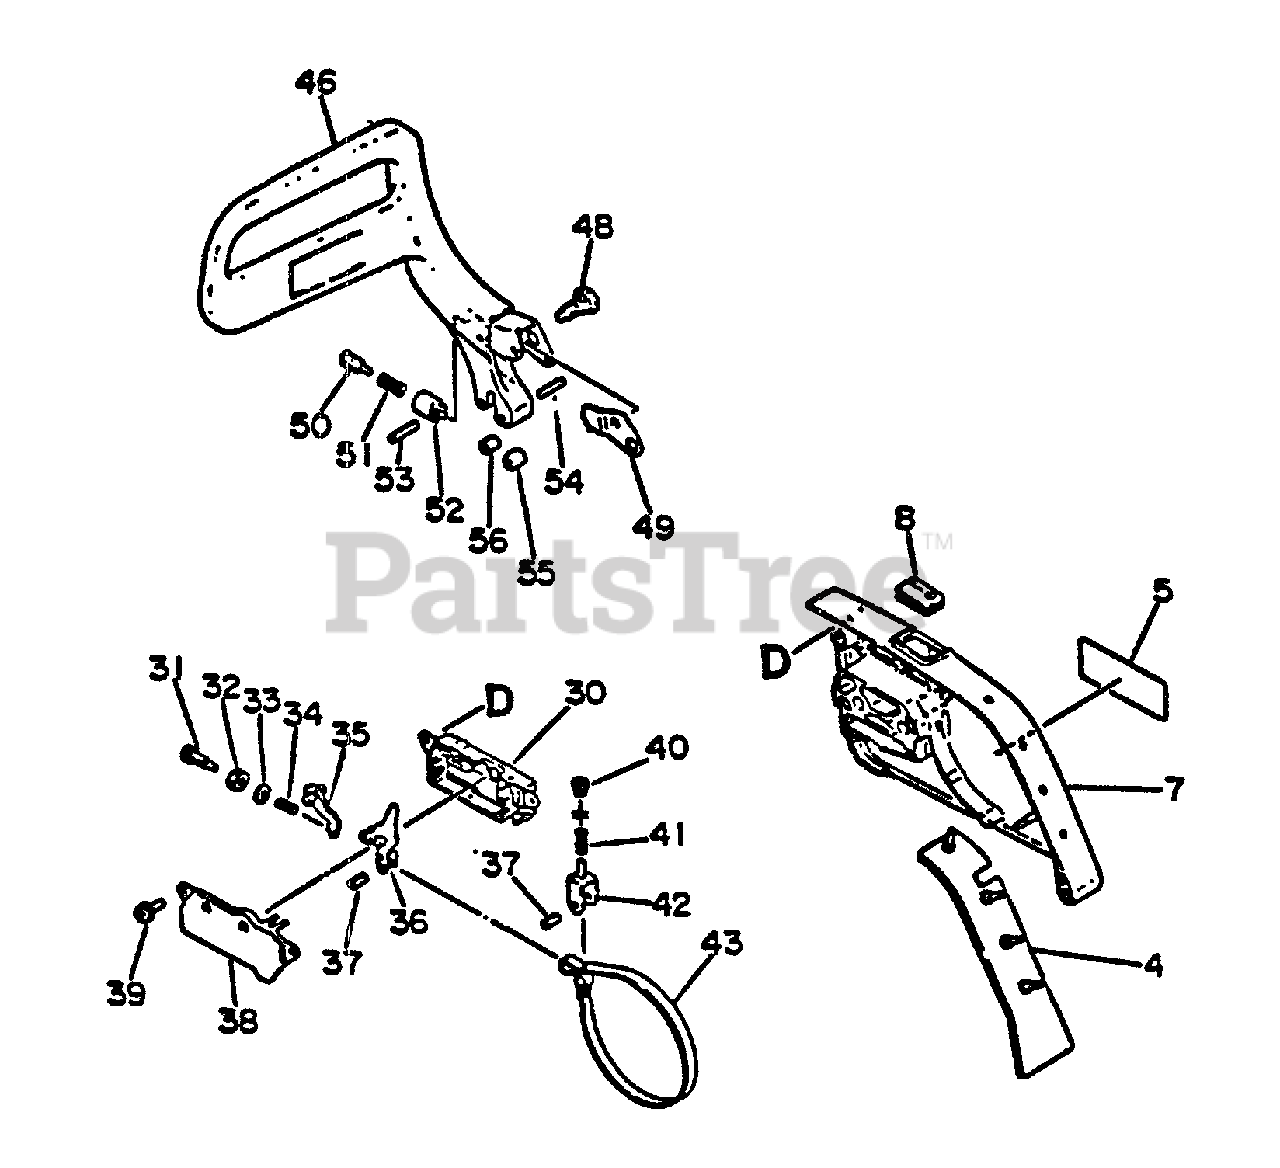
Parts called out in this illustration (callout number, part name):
4	PROTECTOR
5	LABEL - ECHO
7	GUARD, SPROCKET
8	CHAIN BRAKE ASSY
30	COVER, BRAKE
34	SPRING ,BRAKE
35	STOPPER, BRAKE
36	LEVER, BRAKE
37	PIN, SPRING
39	SCREW - 4×10
42	ADJUSTER, BRAKE BAND
43	BAND, BRAKE
46	BRAKE LEVER ASSY
53	PIN 2×20
54	PIN 3×18
55	SPACER
56	SPACER
